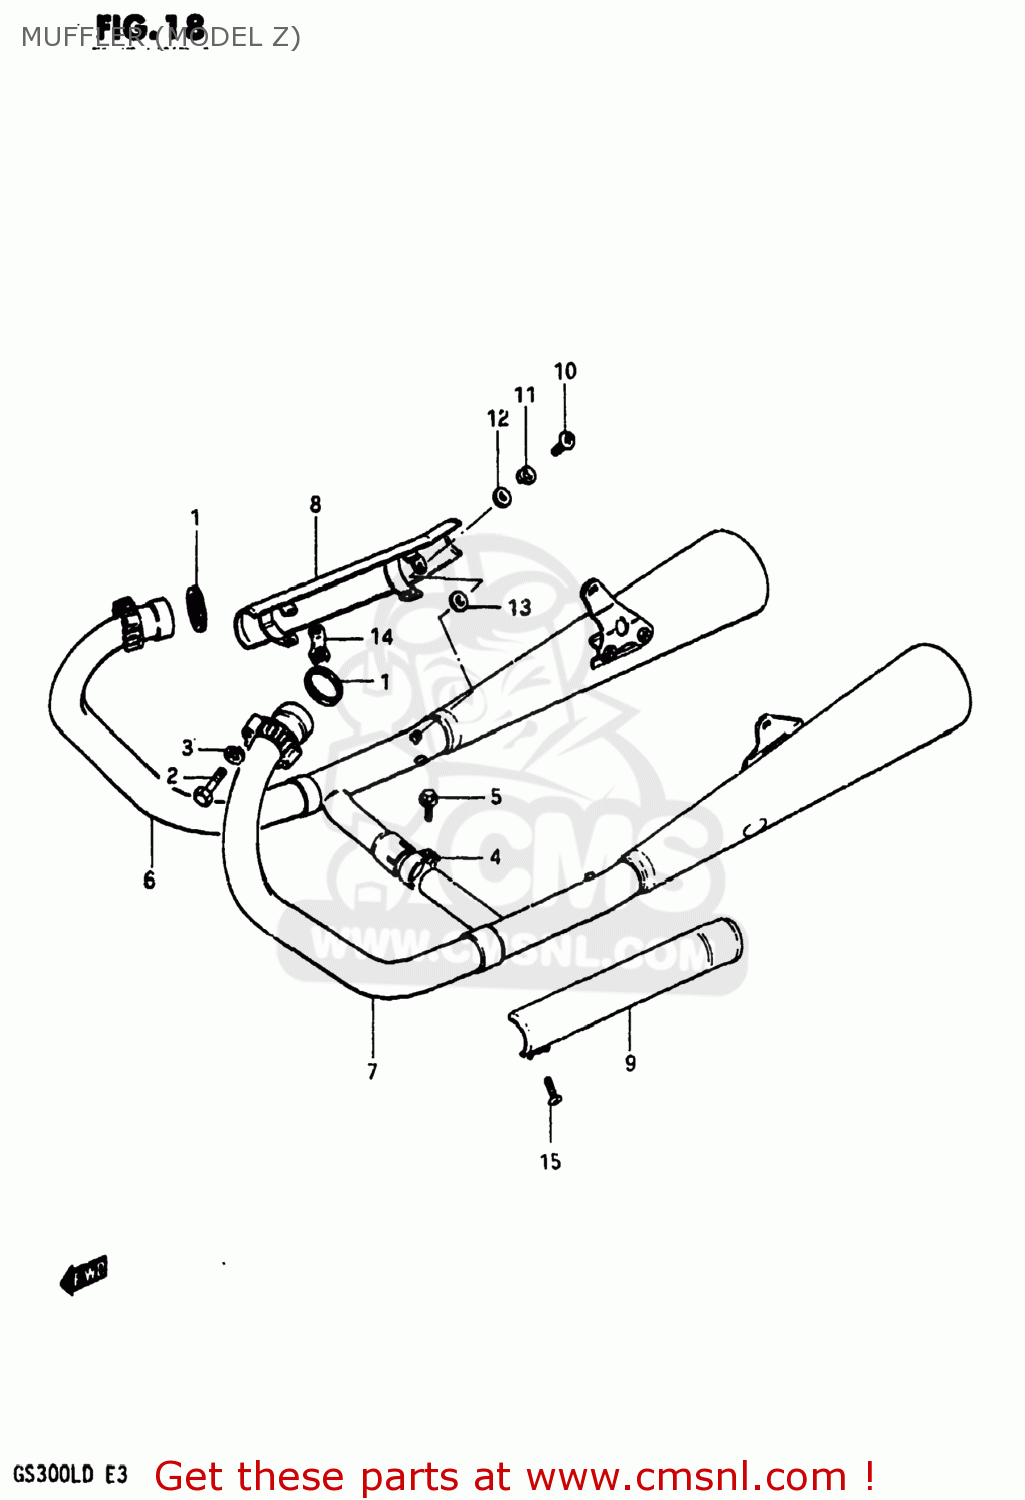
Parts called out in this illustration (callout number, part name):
1	GASKET,EXHAUST PIPE (NAS)
2	BOLT 8X40
3	LOCK WASHER
4	CLAMP
5	BOLT
6	MUFFLER ASSEMBLY
7	MUFFLER ASSEMBLY
8	COVER,MUFFLER,RIGHT
9	COVER,MUFFLER
10	SCREW 6X12
11	LOCK WASHER
12	WASHER
13	GASKET 6.2X12X1.5 (MCA)
14	CLAMP,MUFFLER COVER
15	SCREW
